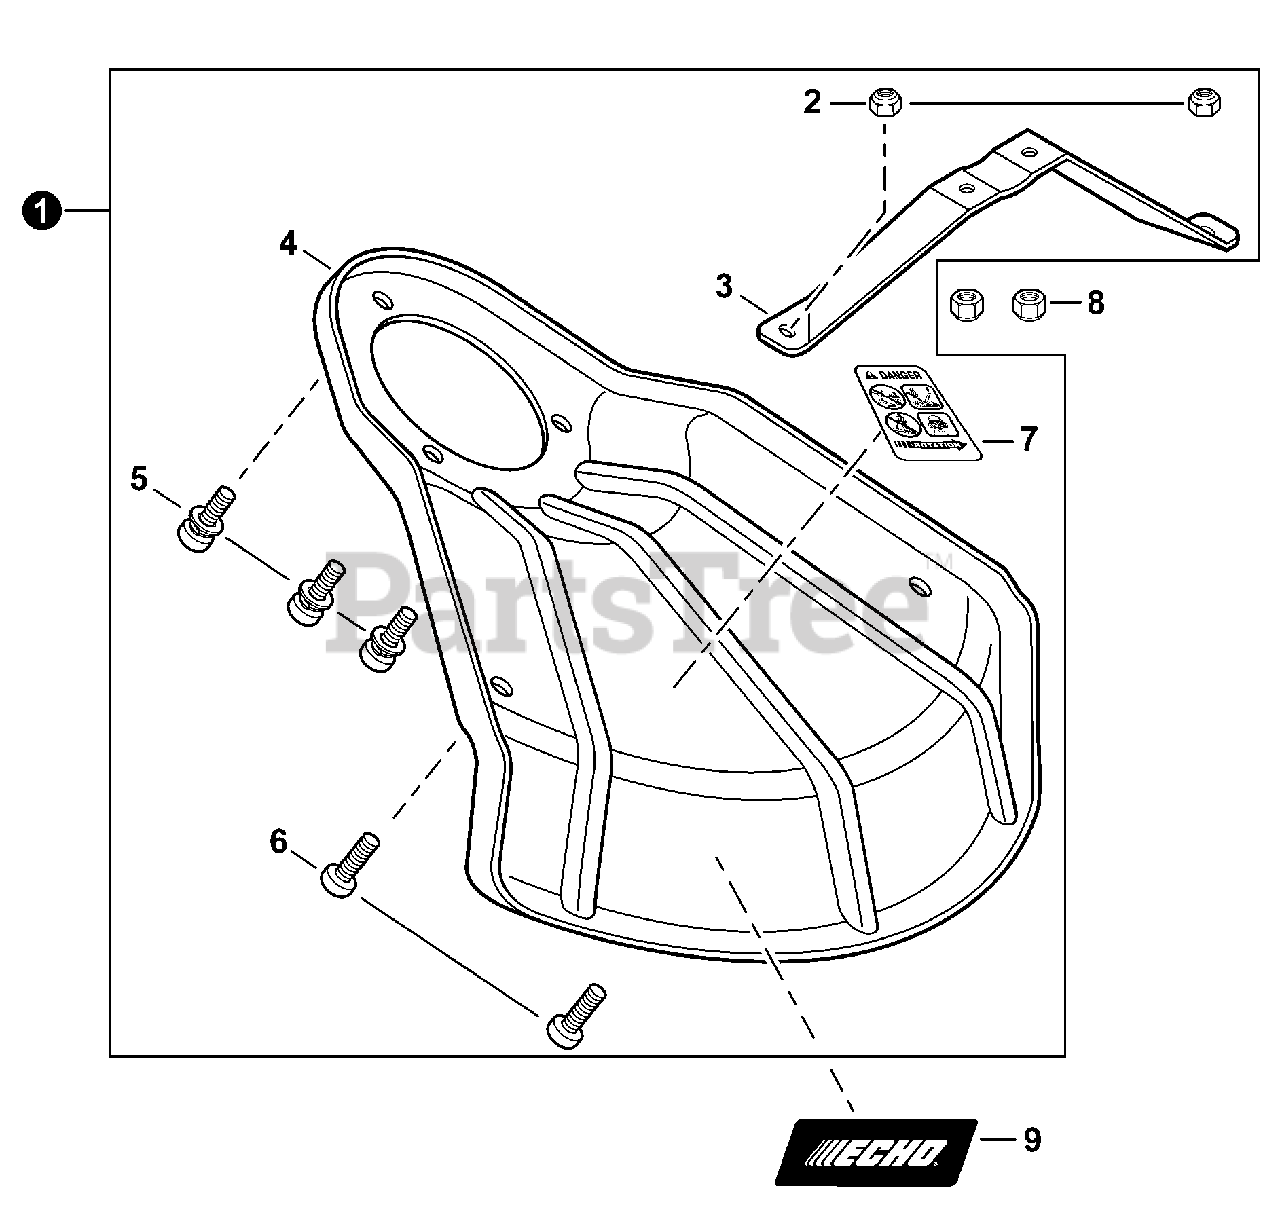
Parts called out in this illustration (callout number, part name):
1	DEBRIS SHIELD KIT - BLADE
2	NUT, LOCK M5
3	BRACKET, SHIELD MOUNTING
4	SHIELD, METAL DEBRIS
5	SCREW 5×10
6	SCREW 5×10
7	LABEL, DANGER
8	NUT, LOCK M5
9	LABEL, ECHO
